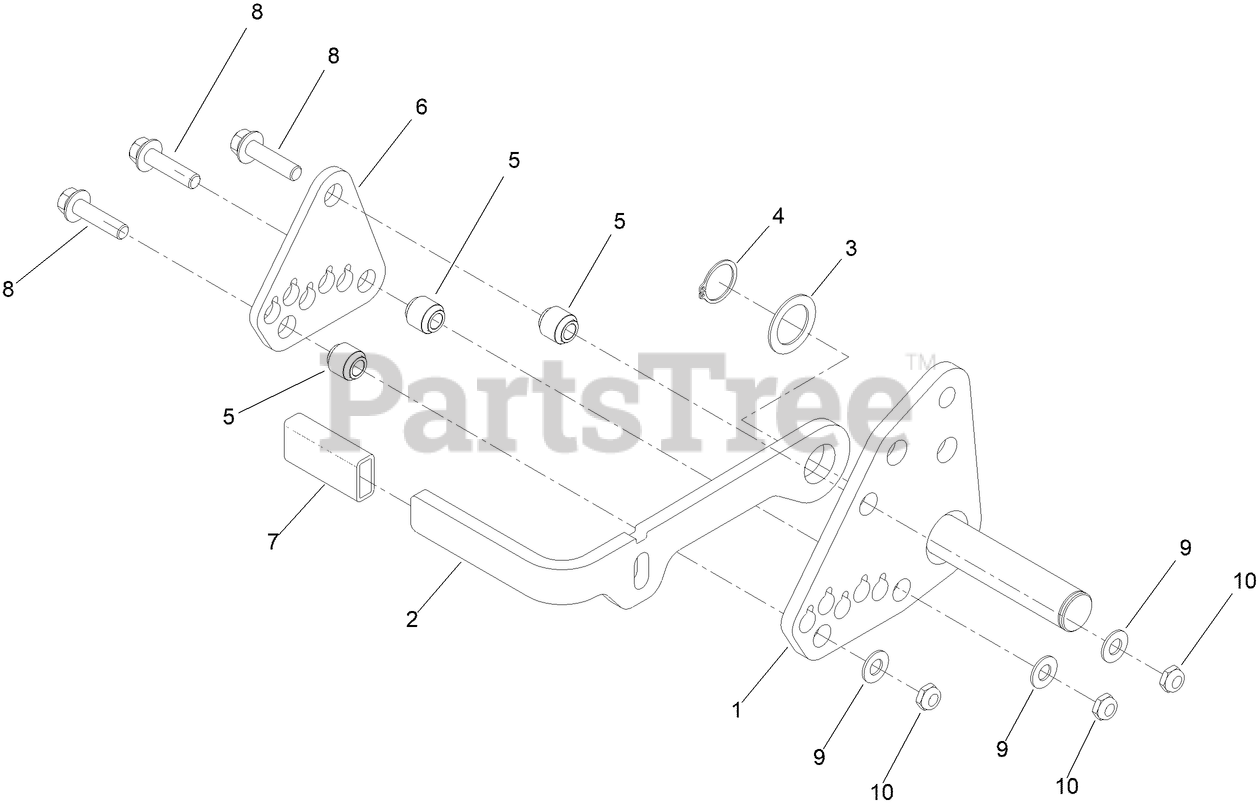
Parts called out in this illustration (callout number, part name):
1	PIVOT ASM-LH HOC
2	LEVER-RAKE, DECK
3	WASHER-THRUST
4	RING-RETAINING
5	SPACER-DOUBLE STEP
6	PLATE-RAKE ADJ, OUTER
7	GRIP-FLAT
8	SCREW-HHF
9	WASHER-PLAIN
